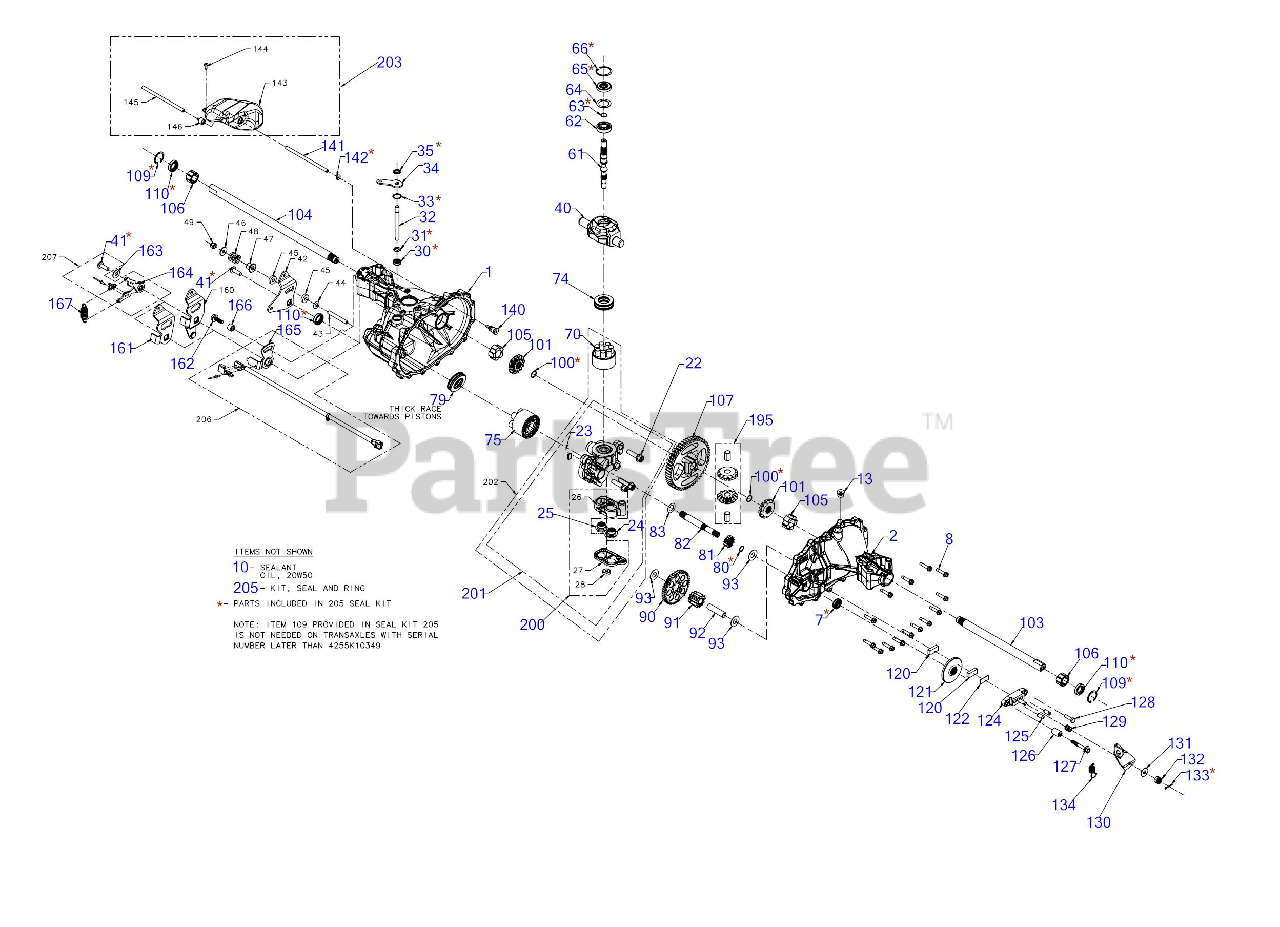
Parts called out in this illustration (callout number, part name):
1	MAIN HOUSING
2	SIDE HOUSING
8	SCREW-WASHER HEA
10	SEALANT-HOUSING
13	PLUG-STRAIGHT THRE
22	SCREW-CAP 3/8-16X1
23	BYPASS PLATE
24	CHECK PLUG ASSEMBLY .044
25	PLUG ASSEMBLY-CHECK
30	SEAL-LIP .375
31	RETAINING RING
32	BYPASS ACTUATOR ROD
33	RETAINING RING
34	BYPASS ARM
35	RETAINING RING
40	TRUNNION SWASH PLATE
41	SCREW 5/16
61	INPUT SHAFT
62	BALL BEARING
63	RETAINING RING
66	RING-RETIAINING
70	7 PISTON BLOCK KIT (8CC)
74	THRUST BALL BEARING
75	BLOCK KIT-5 PISTON
79	THRUST BEARING
80	RETAINING RING .50 EXT
81	13T PINION GEAR
82	MOTOR SHAFT
83	MOTOR SHAFT WASHER
90	GEAR 10T/48T
91	10T JACKSHAFT GEAR
92	JACK SHAFT PIN
100	RETAINING RING
101	GEAR-SPLINED MITER
103	DD AXLE SHAFT 9.754 x .75
104	DD AXLE SHAFT 15.345 x .75
105	INBOARD BUSHING
106	OUTBOARD BUSHING
107	54T BULL GEAR
109	RETAINING RING
120	BRAKE PUCK
121	ROTOR-BRAKE
122	PLATE-PUCK
124	BRAKE YOKE ASSEMBLY
125	ACTUATING PIN
126	SPACER-TORSION SPG
127	BOLT-SPECIAL FLANG
128	HEX SCREW
129	BRAKE SPRING
130	ARM-BRAKE
131	FLAT WASHER
132	NU-HEX INS JAM
133	COTTER PIN-3/32
134	BRAKE SPRING
140	FITTING 5/16 SAE 5/32 TUBE
141	HOSE-DRAIN .28X.15
161	RETURN CONTROL ARM
162	HEX SCREW FLANGE
163	FLAT WASHER
164	BI DIRECTIONAL RETURN ASSEMBLY
165	NEUTRAL ARM ASSEMBLY
167	EXTENSION SPRING
195	MITER GEARS KIT W/PINS
200	FILTER KIT
201	CENTER SECTION ASSEMBLY W/FILTER
203	EXPANSION TANK KIT
